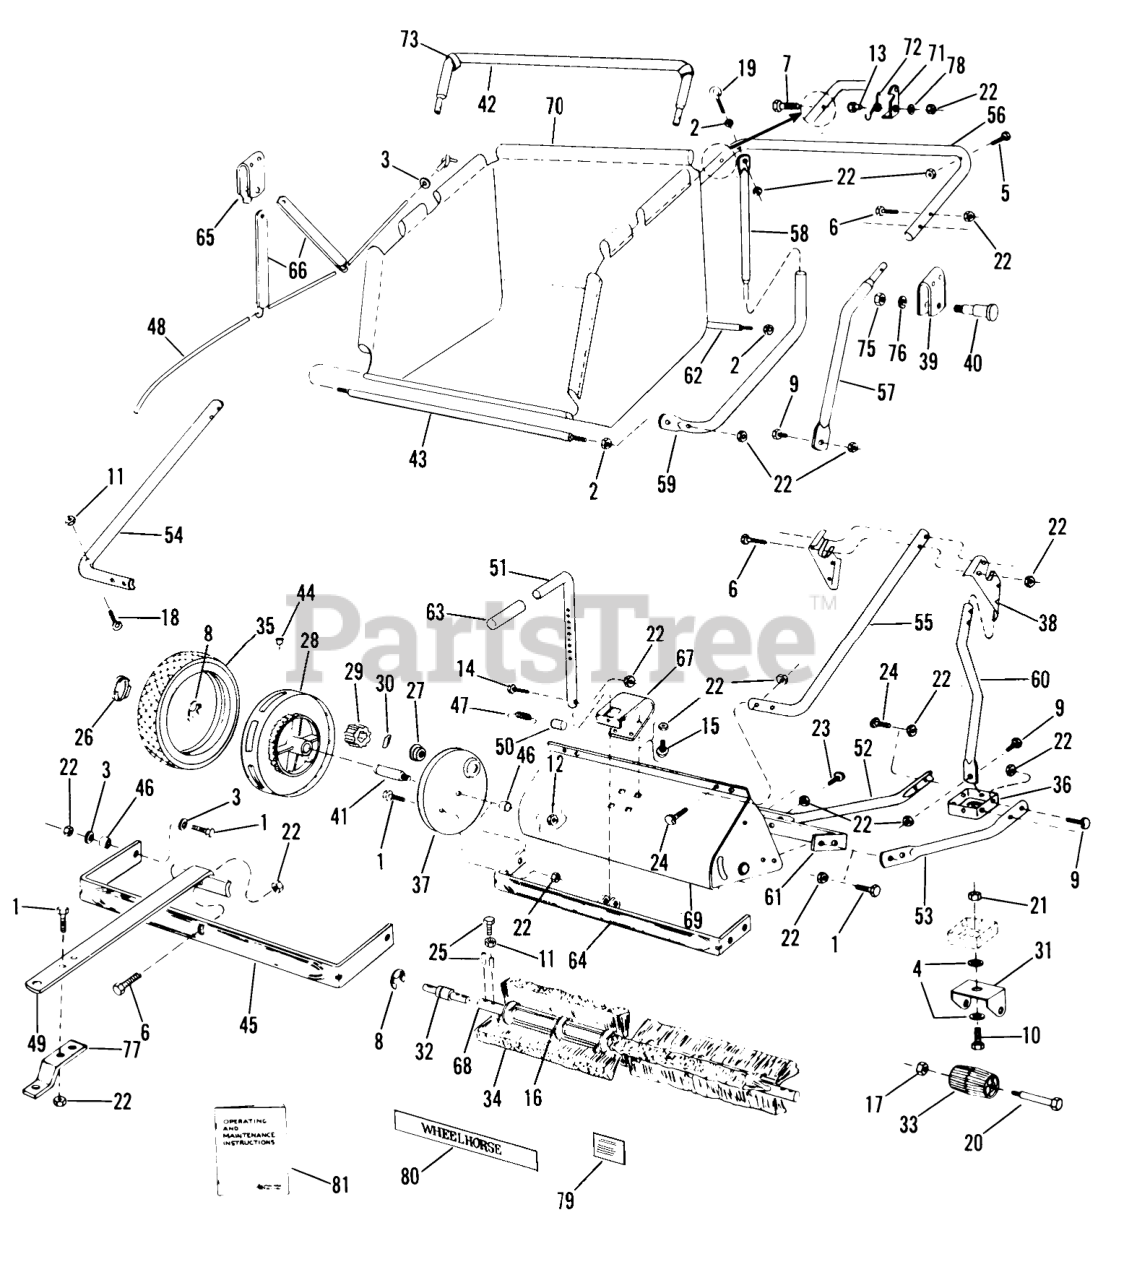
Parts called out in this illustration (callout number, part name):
1	Bolt
2	Nut
3	WASHER 5/16 SAE
4	Washer
5	Bolt
6	Bolt
7	Bolt
8	RING LAM L 262
9	H H C S
10	Bolt
11	Nut
12	NUT-6
13	Bolt Nut 5/16-18
14	HHCS
15	Bolt-Carriage 5/16-18 x 5/8
16	SPRING
17	NUT-6
18	Bolt-Eye 1/4-20 x 2
19	Bolt-Eye 5/16-18 x 2 3/4
20	STUD CASTER
21	Eslok Nut
22	Nut
23	Bolt-Tube 5/16-18 x 1 1/4
25	ROLLPIN 3/16 X 7/8
25	Bolt
26	PLUG BUTTON
27	BEARING
28	Wheel Ass-y.
29	PINION GEAR
30	PINION PAWL
31	Bracket-Caster
32	BRUSH STUB AXLE
32	AXLE BRUSH STUD
33	CASTER ROLLER
34	STRIP
34	STRIP BRUSH
35	Tire 10 x 2.25
36	Caster, Plate Ass-y.
37	SHIELD WHEEL
38	Bracket-Frame Pivot
39	Bracket-Hamper Pivot
40	PIVOT PIN
41	WHEEL STUD
42	Tube-Pivot Stand
43	Rod-Hamper Tie
44	Oiler
45	Hitch-U Bar
46	Spacer
47	Spring-Adjustment
48	Dump Rope
49	Tongue-Hitch
50	TUBE SPRING
51	TUBE ADJUSTING
52	Brace-Pivot Stand
54	Tube R.H. Support
55	Tube L.H. Support
56	Tube Top Hamper
57	Tube Side Hamper
59	Tube Bottom
60	Support R.H. Pivot
60	Support L.H. Pivot
61	Stiffner-Bar
62	Rod-Rear Hamper
64	Bumper Ass-y.
65	ASSY BRACKET
66	Lever-Dump
67	Bracket-Adjustment
68	ASSY BRUSH AXLE & DS
68	Axle-Brush
69	Shield-Ass-y.
70	HAMPER ASSY
70	Hamper-Ass-y.
71	Latch-Hamper
72	Spring-Latch
73	Sleeve-Rubber
75	NUT-6
76	LOCKWASHER
77	BRACKET-HITCH PIN
78	Washer, 7/16
79	Decal Adjustment
80	DECAL-WHEEL HORSE
81	Operating and Maintenance Instructions
